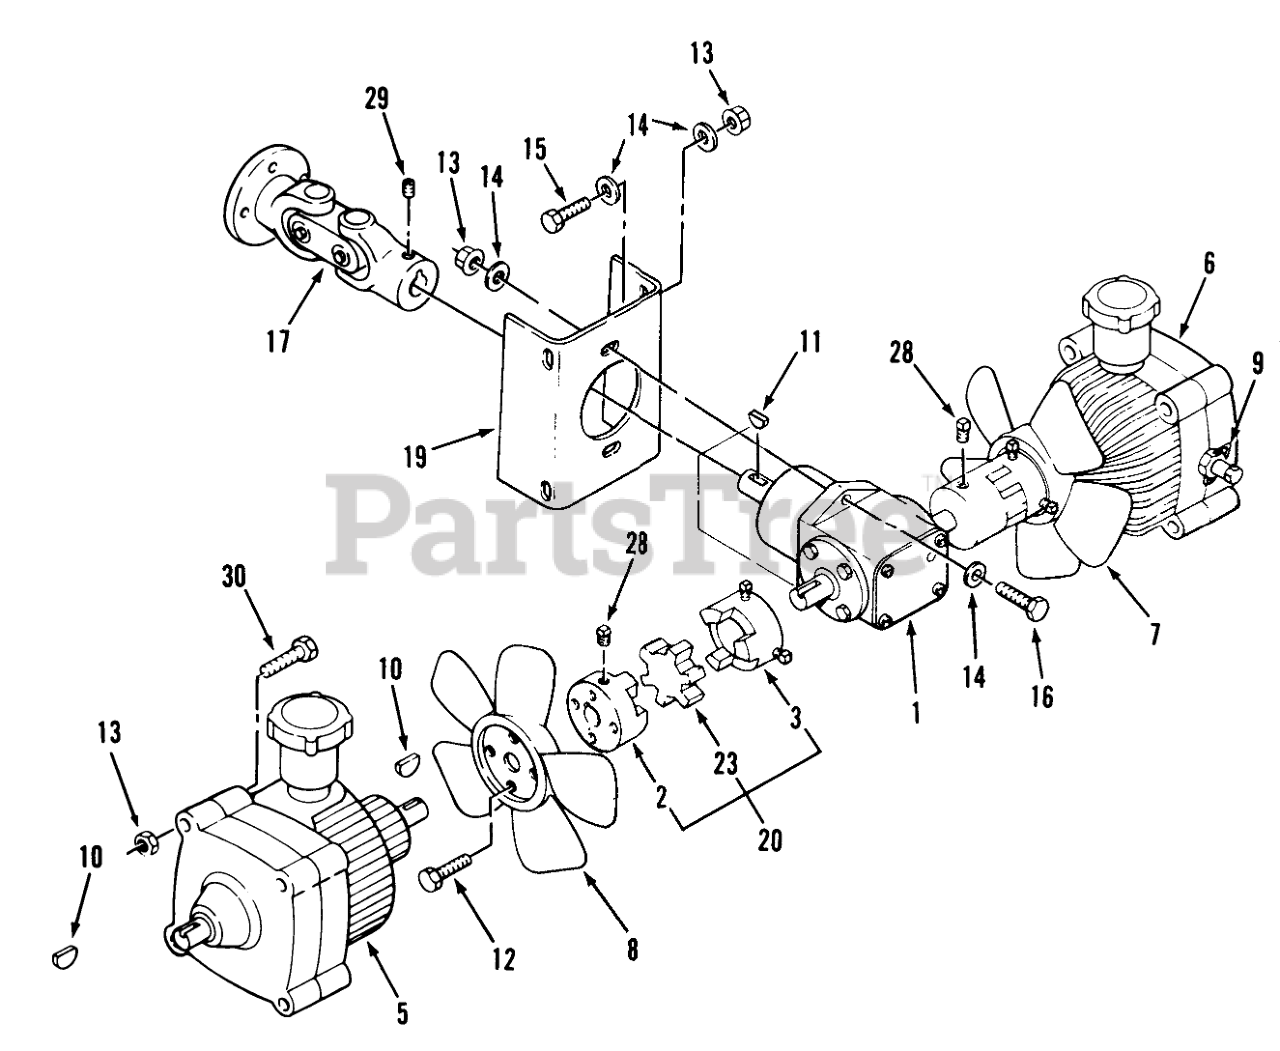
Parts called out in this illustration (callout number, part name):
1	GEAR BOX-T
2	COUPLING-KEYED
3	COUPLING-KEYED
5	TRANS-HYDRO CCW.
6	TRANS-HYDRO CW
7	Fan-LH, Clockwise
8	BLADE-FAN R.H.
9	CLIP-DUMP VALVE
10	KEY-HIPRO
11	KEY-HI-PRO
12	Screw
13	NUT-LOCK, NI
14	WASHER-FLAT
15	SCREW-HH
16	SCREW-HH
17	U-JOINT ASSY W/FLANGE
19	BRACKET-GEAR BOX B
20	Coupler-Complete (Incl. Items 2, 3, & 23)
23	SPIDER-COUPLING
28	1/2X1 CUP PT SETSCREW
29	SCREW-SET, HSH
30	SCREW-HH
